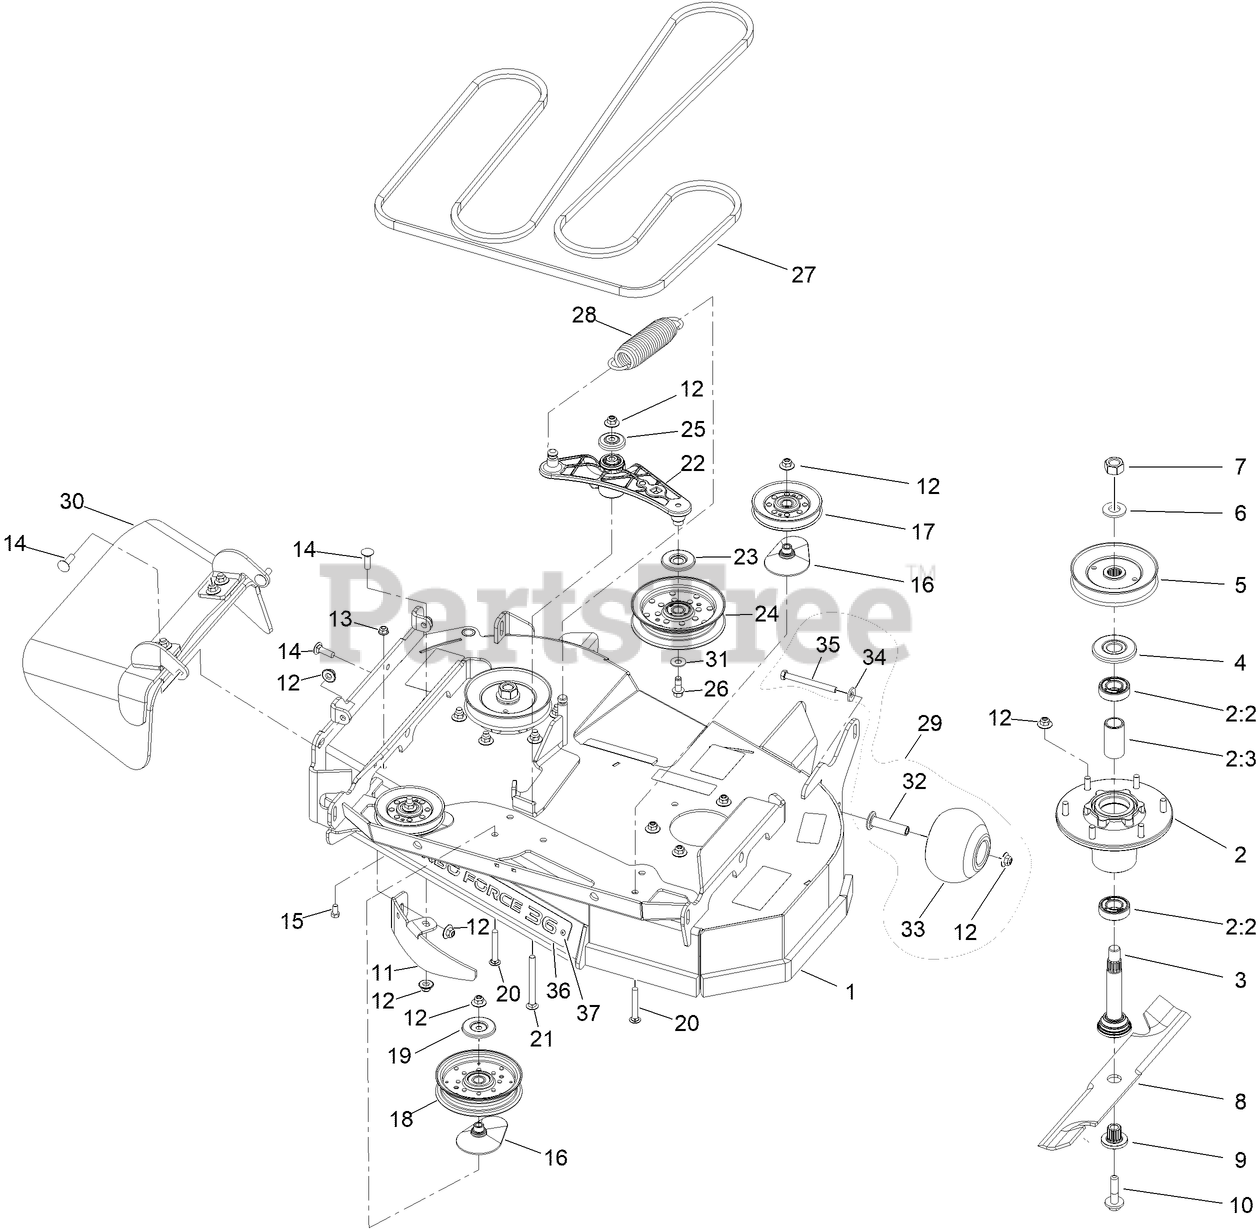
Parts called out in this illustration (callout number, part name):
1	ASM-DECK W/DECALS
2	ASM-CUTTER HSG WITH BEARINGS
2:2	BEARING-BALL
2:3	SPACER-BEARING
3	ASM-SPINDLE AND SEAL
4	GUARD,BEARING TOP .989
5	SHEAVE-BLADE DRIVE
6	WASHER
7	NUT-HEX
8	BLADE-HIGH FLOW
9	Bushing, Splined
10	SCREW-SEMS
11	BAFFLE, DOGLEG
12	NUT-FLANGE, NI
13	NUT-HF, NI
14	BOLT-CARR
15	SCREW-HH
16	SPACER-PULLEY
17	IDLER - V 4.13 EOD-A
18	PULLEY-IDLER, FLAT
19	SHIELD-DUST
20	SCREW-CARR
21	SCREW-CARR
22	ASM.-ARM, IDLER
23	SHIELD-GUARD, DUST
24	IDLER-PULLEY, FLAT
25	GUARD-TOP
26	SCREW-HFH
27	BELT-V
28	SPRING-EXTENSION
29	KIT, ANTI-SCALP ROLLER
30	RUBBER DEFLECTOR ASM
31	WASHER-FLAT
32	AXLE, ROLLER
33	ROLLER-SCALP, ANTI
34	WASHER-BELLEVILLE
35	SCREW-HH
36	PLATE-BADGE [BLACK]
37	RIVET-TRIFOLD
